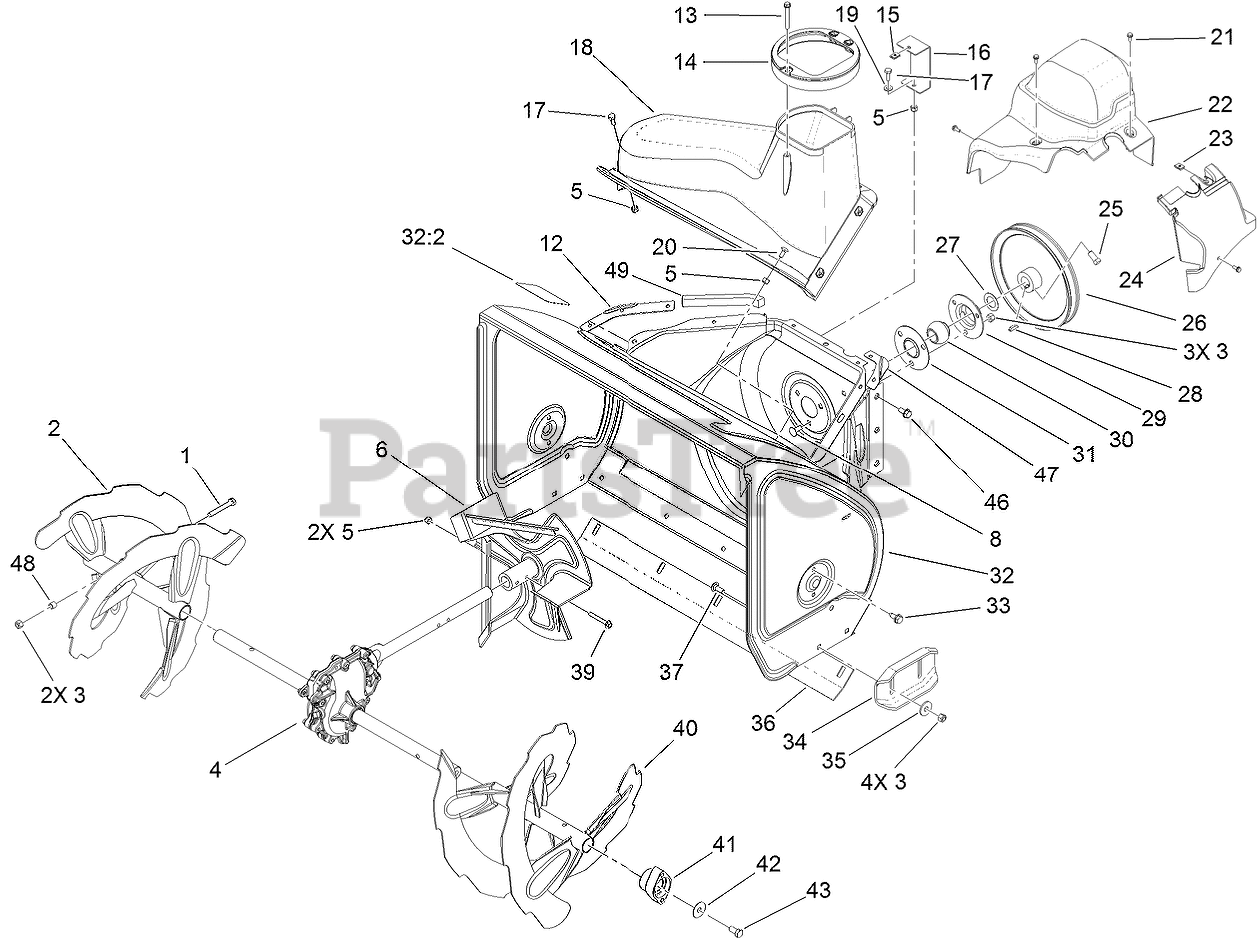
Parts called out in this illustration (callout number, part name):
1	SCREW-HH
2	RH AUGER ASM
3	NUT-LOCK, NI
4	26 INCH AUGER GEARCASE ASM
5	NUT-LOCK, NI
6	IMPELLER ASM
8	SCREW-CARR
12	SEAL-FLANGE, COVER
13	SCREW-PLASTITE
14	GUIDE-CHUTE
15	NUT-SPEED, U-TYPE
16	BRACKET-COVER, CLIP NUT
17	SCREW-HH
19	WASHER-FLAT
20	BOLT-CARR
21	SCREW-HWH
22	COVER-BELT
23	NUT-SPEED
24	COVER-EXTENSION, BELT
25	SCREW-SET, SQH
26	PULLEY-IMPELLER
27	WASHER-THRUST
28	KEY-WOODRUFF
29	FLANGE-CUP, BEARING
30	BEARING-BALL
31	FLANGE-CUP, BEARING
32	HOUSING-AUGER, 26 INCH
32:2	DECAL-DANGER, AUGER
33	SCREW-HWHTF
35	WASHER
36	SCRAPER-FIXED
37	SCREW-CARR
39	SCREW-HHF
40	LH AUGER ASM
41	BEARING-AUGER
42	WASHER
43	SCREW-HH
46	SCREW-HWHTF
48	SPACER
49	SEAL-HOUSING
